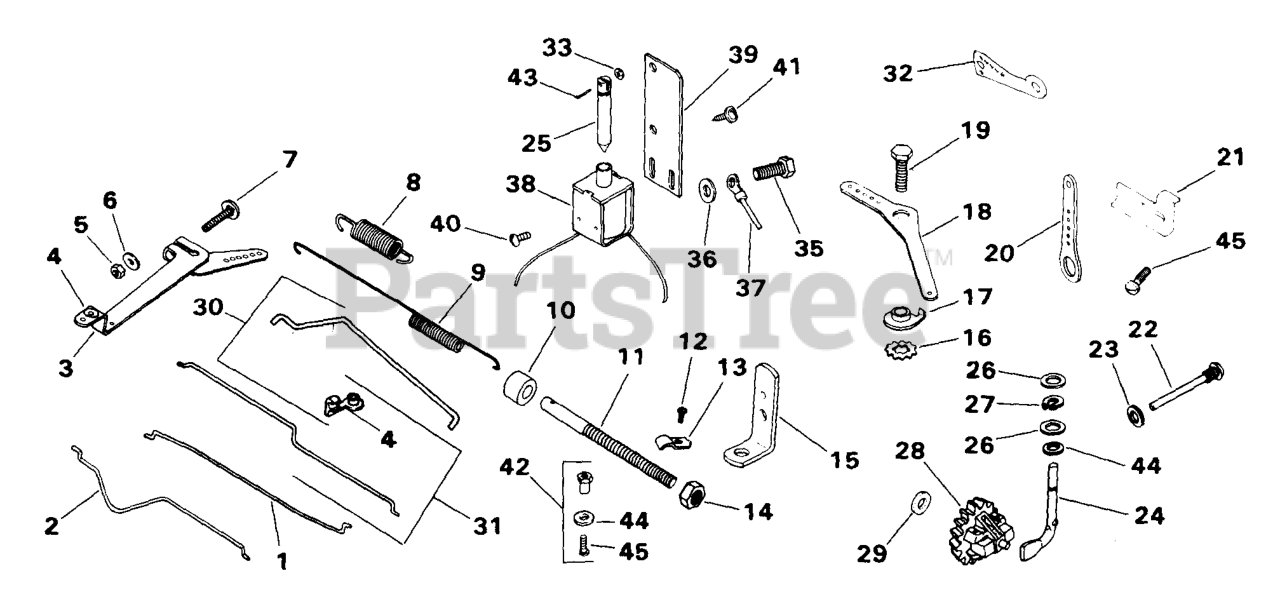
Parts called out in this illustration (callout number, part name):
3	Arm, Governor
4	Bushing, Linkage
5	Nut, Hex. 1/4-20
6	Washer, Plain 1/4"
7	Bolt, R.H. Sq. Neck 1/4-20x1"
8	Spring, Governor
12	Screw, Hex. Wash. Hd. 10-24x3/8"
13	Clamp, Cable
20	Lever, Speed Control
21	Stop, High Speed
22	Pin, Governor Stop
23	Washer, Plain 1/4"
24	Shaft, Governor
26	Washer, Plain 1/4"
27	Retainer, Governor
28	Kit, Governor Gear
29	Washer, Thrust
31	Kit, Governor Linkage
44	Washer, Plain 1/4"
45	Screw, Hex. Wash. Hd. 1/4-20x3/4"
